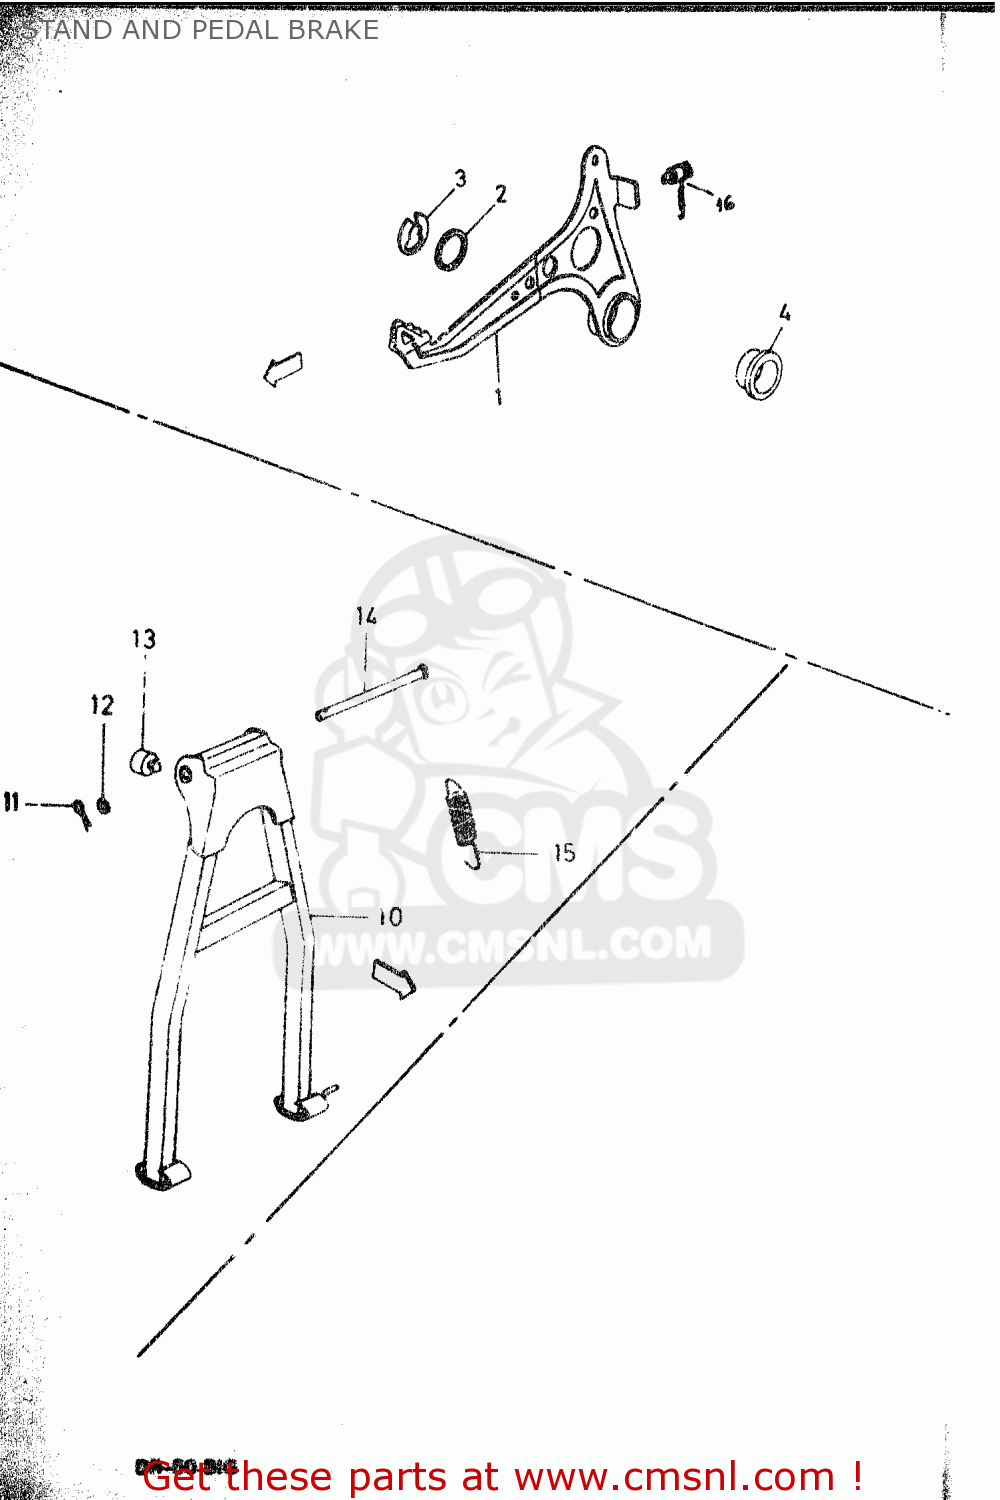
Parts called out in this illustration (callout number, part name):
1	PEDAL, BRAKE
2	WASHER (16.1X25.6X2)
3	E RING (E 16 DIN 471)
4	BUSH PLASTIC
10	CENTER STAND
11	SPRING PIN (3X20 DIN 94)
12	PLAIN WASHER B10 DIN 433
13	CUSHION
14	BOLT
15	SPRING
16	SWITCH, REAR BRAKE
